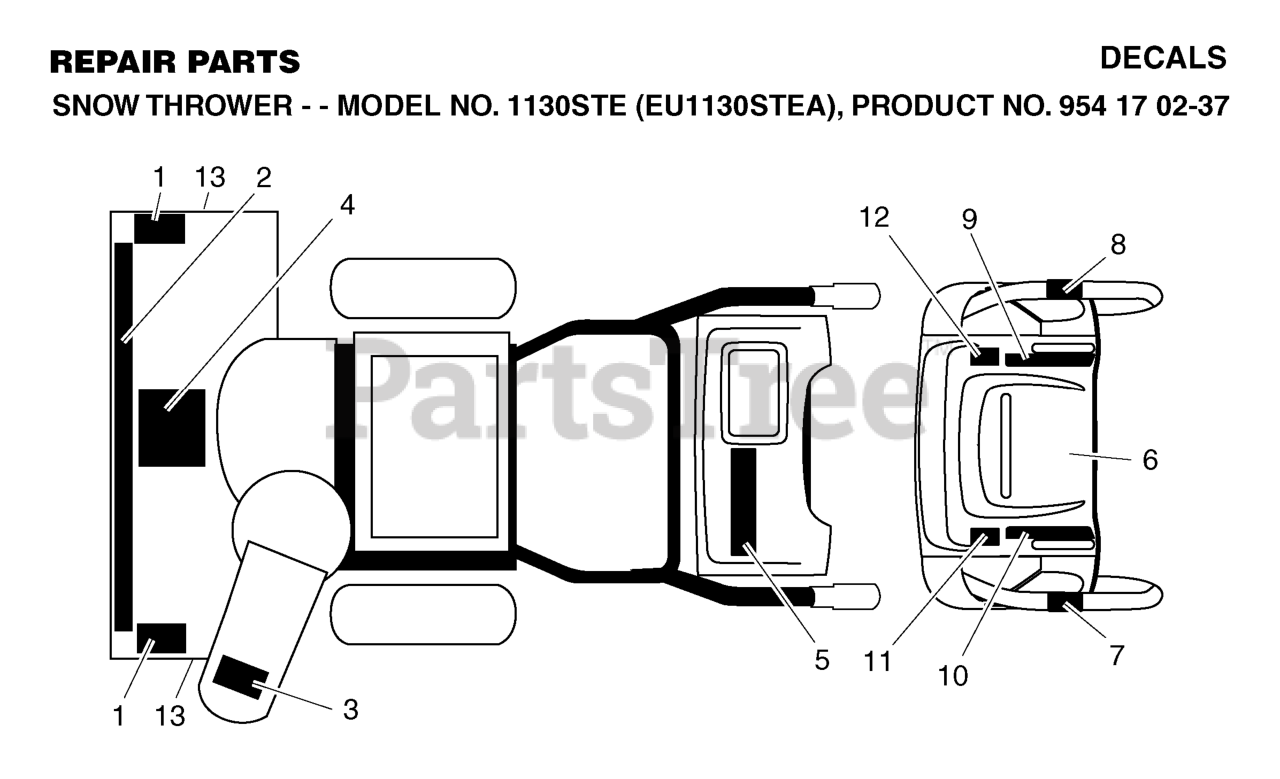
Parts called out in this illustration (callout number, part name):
4	DECAL.AUGER."
6	DECAL.CONSOLE.INSTRUCTION
10	DECAL.REM.DEFLECTOR.LT
11	DECAL, LH TRIGGER
12	DECAL, RH TRIGGER
13	DECAL, HUSQVARNA
